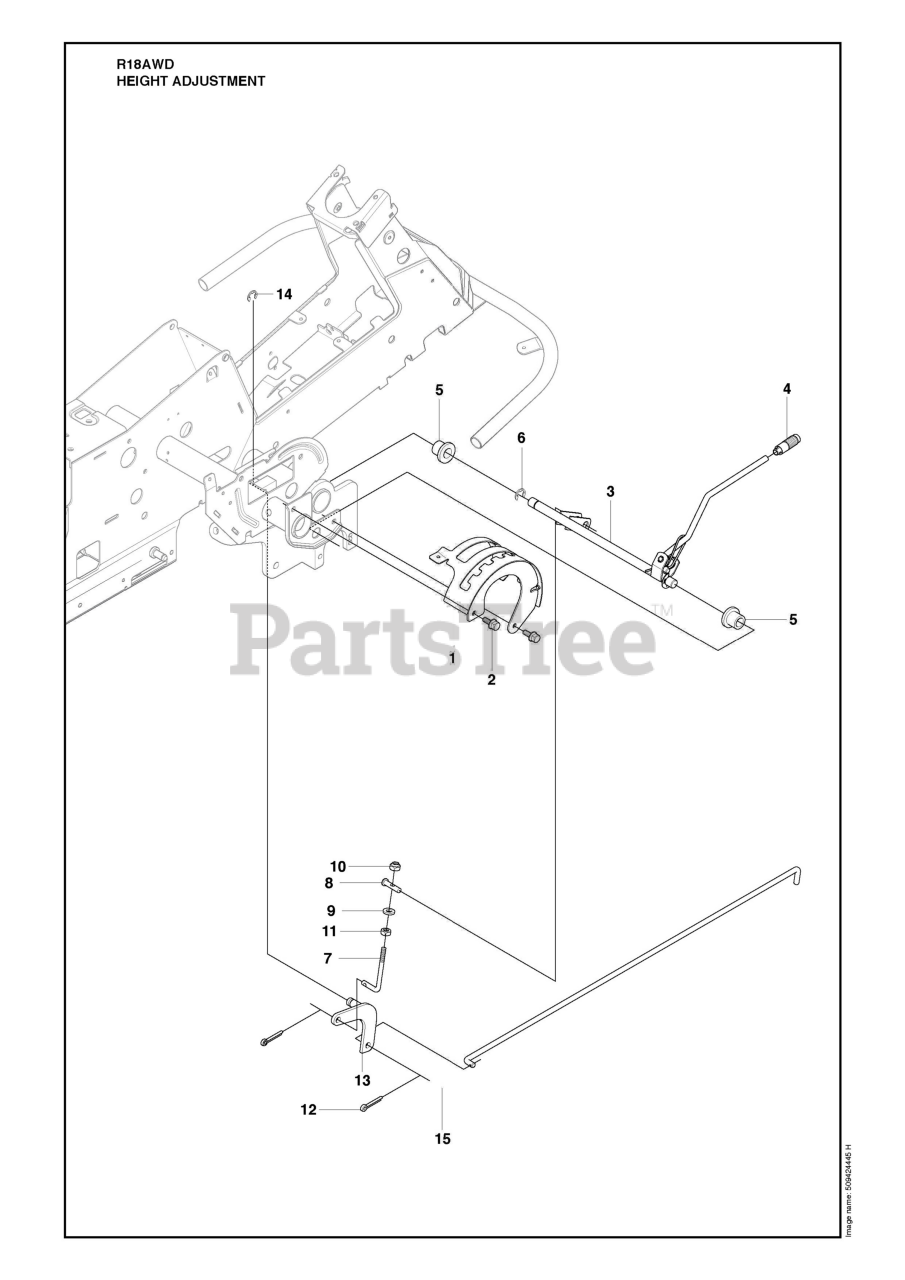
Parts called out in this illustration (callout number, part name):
1	CONTROL PLATE
3	HEIGHT ADJUSTER
4	GEAR STICK KNOB
5	BUSHING
9	WASHER
10	LOCKNUT M8
11	NUT
14	RETAINING RING
15	CONNECTION ROD
